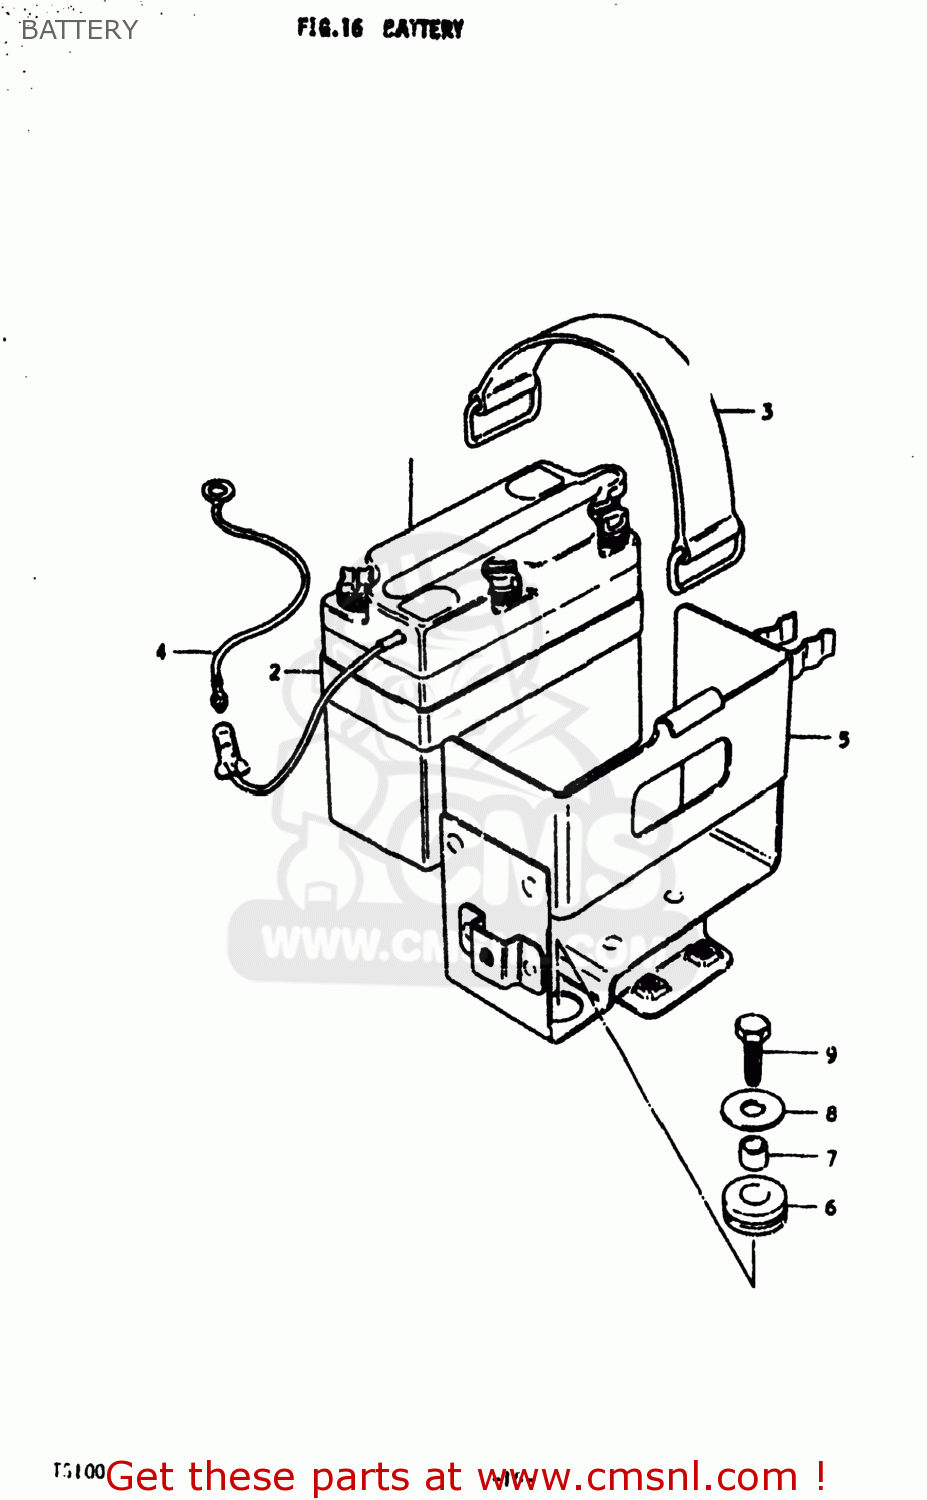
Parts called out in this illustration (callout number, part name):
1	BATTERY(6N4B-2A,6V4.2AH)
2	PROTECTOR,BATTERY
3	BAND
4	LEAD WIRE
5	HOLDER,BATTERY
6	CUSHION
7	SPACER (7X9X7)
8	WASHER (6.5X20X1.2)
